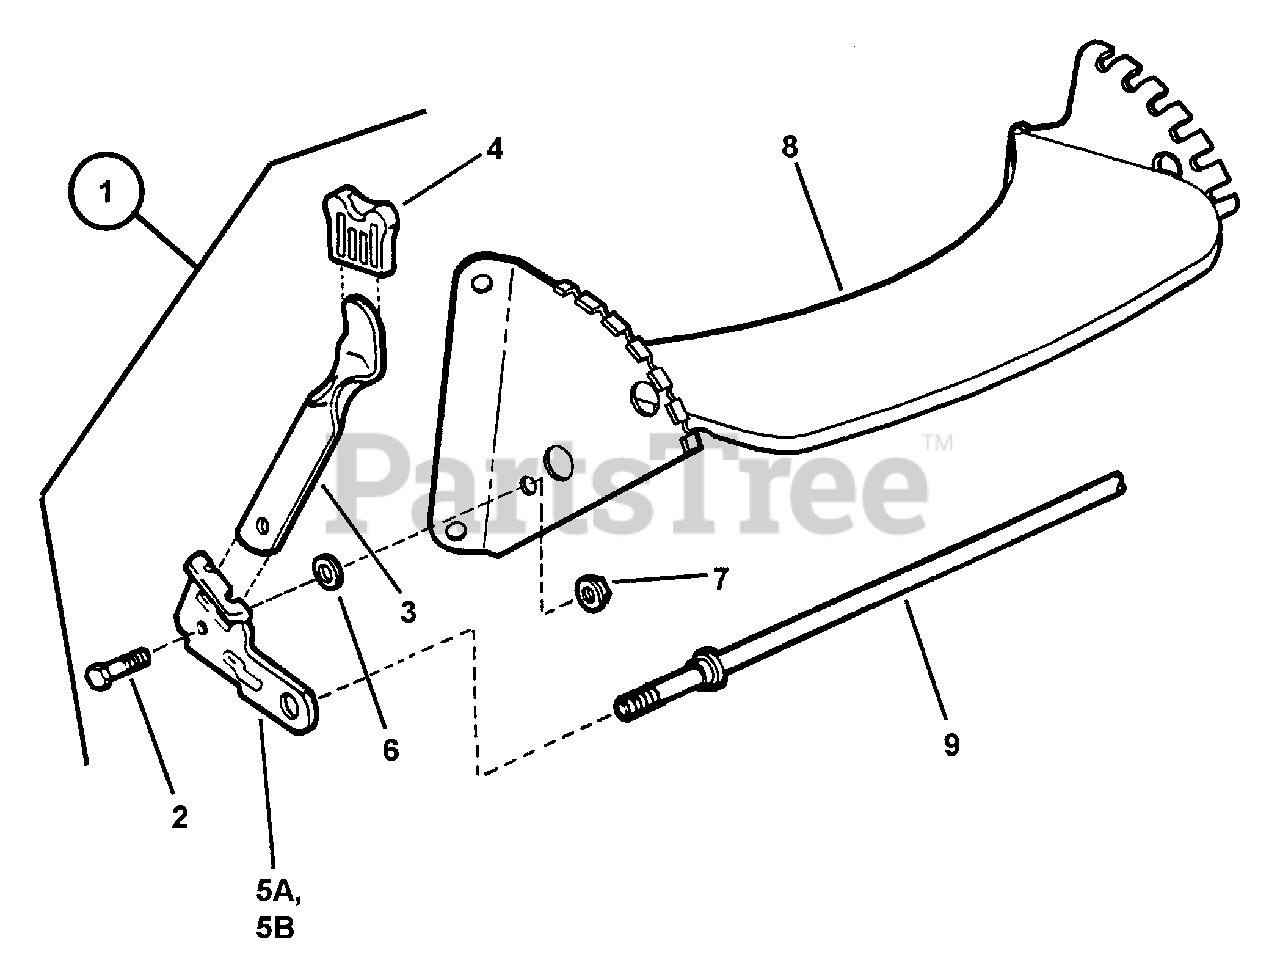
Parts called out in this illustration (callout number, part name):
1	ASSEMBLY, Arm Right Wheel
2	BOLT, 5/16-18 x 3/4" Shoulder
3	LATCH, Height
4	GRIP, Latch
5A	ARM, Right Wheel (Round Hole)
6	RETAINER, 5/16 Bolt
7	NUT, 5/16-18 Hex Flange Lock, Grade 5
8	BRACKET, Front Wheel
9	AXLE
